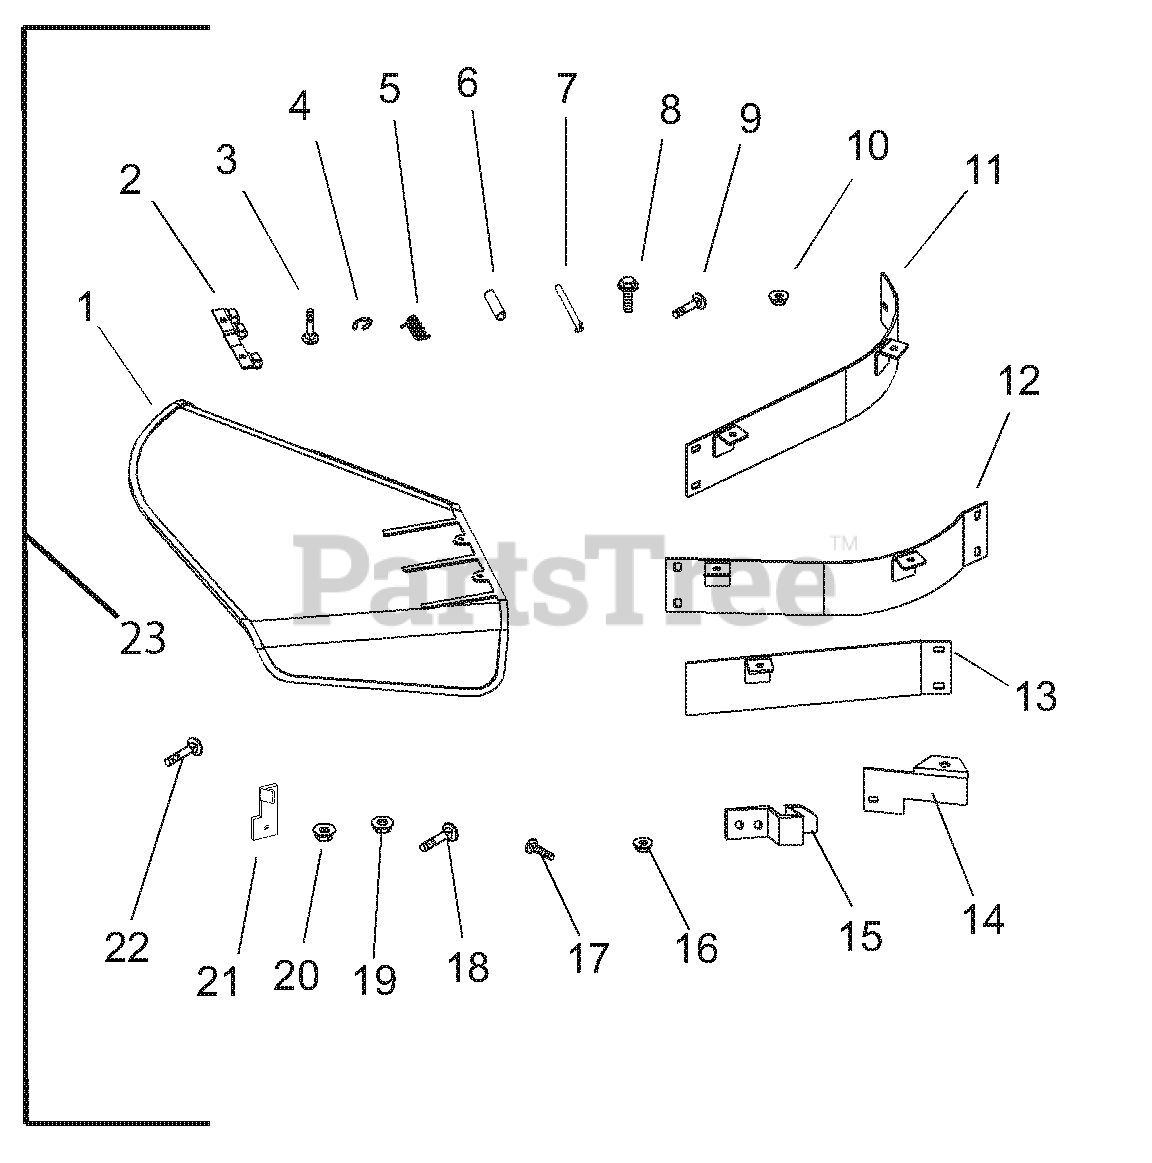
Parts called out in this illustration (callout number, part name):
1	DEFLECTOR, CHUTE
2	HINGE PLATE
3	@BLT-RDHDSQNK .25-20X.75 G5YZ
4	RG-RTNG-EXT .312X.025
5	SG-TORS .095X.50X 1.0
6	BSHG-SLV .334 X .502 X 1.437
8	BLT SERHFWH .31-18X.62 GR5YWZC
9	@BLT-RHDSSQNK .31-18X.62 G5YZ
10	@NUT-LK-NYL-FLG .31-18 YWZC
11	BAFFLE - LEFT FRONT - 40"
11	BAFFLE - LEFT FRONT - 44"
12	BAFFLE - CENTER FRONT - 40"
12	BAFFLE - CENTER FRONT - 44"
13	BAFFLE - RIGHT FRONT - 40"
13	BAFFLE - RIGHT FRONT - 44"
14	DEFLECTOR-40"
14	DEFLECTOR-44"/48"
15	FLAT SPRING
16	@NUT-LK-TOP-FLG .25-20 YWZC
17	@BLT-RDHDSQNK .25-20X.50 G5YZ
18	@BLT-RDHDSQNK .38-16X1.25 G5YZ
19	@NUT-LK-NYL-FLG .38-16 YWZC
20	@NUT-SPNLK-FLG .375-16 YWZC
21	BRACKET, CHUTE LOCK
22	@BLT-RDHDSQNK .38-16X.75 G5YZ
23	KIT,40"CE SIDE DISCHARGE
23	KIT,44"CE SIDE DISCHARGE
